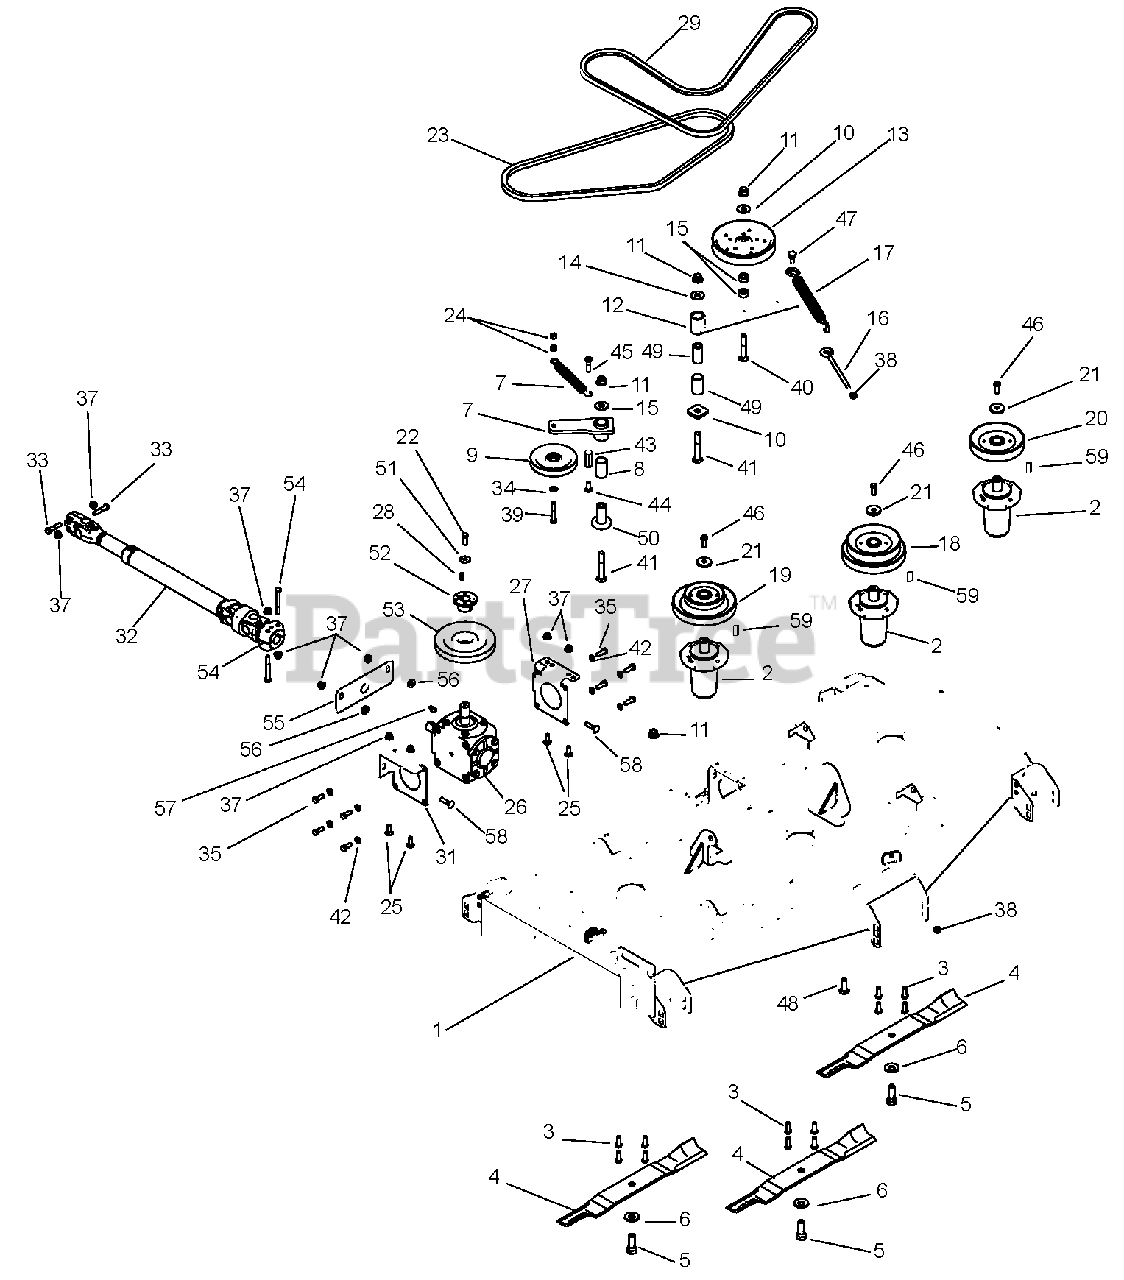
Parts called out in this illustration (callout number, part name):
1	Weldment, 60" Side Discharge Deck (OFM)
2	Assembly, Spindle
3	Bolt, Hex .38-16 x 1.00 EP30
4	Blade, Mower (20.50")
5	Bolt, Hex .62-18 x 1.75 Grade 8
6	Washer, Bellville .63 x 1.625 x .14
7	Weldment, Idler Pivot Arm
8	Bushing, 1.00 x 1.125 x 1.937
9	Sheave, .38" ID x 5.00" OD V-Idler
10	Washer, Flat .640 x 1.75 x .250
11	Nut, Nyloc Flange .50-13
12	Idler Pivot Arm Weldment- Black
13	Idler, Flat-Pulley 6.75 x .510
14	Washer, Flat-Steel .563 x 1.38 x .109
15	Bushing, Spacer .502 x .997 x .50
16	Bolt, .38-16 x 5.50 .62 Diameter Eye
17	Spring, Extension
18	Pulley, Double 1" ID x 6.75" OD
19	Pulley, Double 1.0" ID x 6.75" x 4.25" OD
20	Pulley, V-1" ID x 6.75" OD
21	Washer, Flat Steel .406 x 1.50 x .245
22	Bolt, Hex .38-16 x 1.00 EP30
23	Belt, B 63.00 Raw Cogged
24	Nut, Locking-Center .38-16
25	Bolt, Round Head Square Neck .38-16 x 1.25
26	Gear Box,Right Angle 1.05 x 1.0
27	Bracket, Gear Box Mounting Left Hand
28	Key, Straight .25 x .75 x .25
29	Belt, B 86.00 Wrapped
30	Washer, Flat Steel 1.00 x 1.505 x .062
31	Bracket, Gear Box Mounting Right Hand
32	Shaft, PTO Drive Assembly
33	Bolt, Hex .38-16 x 1.175
34	Washer, Flat Steel .406 x .812 x .065
35	Bolt, Hex .38-16 x 1.00 Grade 8 EP30
36	Spring, Extension
37	Nut, Nylon Locking Flange .38-16
38	Nut, Hex .38-16
39	Bolt, Hex .38-16 x 2.25
40	Bolt, Roundhead Squareneck .50-13 x 3.00
41	Bolt, Roundhead Squareneck .50-13 x 3.50
42	Washer, Lock .375 x .115
43	Nut, Coupling .375-16 x 1.75
44	Bolt, Roundhead Squareneck .38-16 x 1.00
45	Bolt, Hex .38-16 x 1.50
46	Bolt, Hex 3/8-16 x 2.75 Grade 5
47	Bolt, Shoulder Hex .38-16 x .30
48	Bolt, Roundhead Squareneck .50-13 x 1.50
49	Bushing, Spacer, .505/.500 x .999/.996 x 2.05/2.03
50	Pedestal, Bearing
51	Washer, Flat Steel .375 x 1.125 x .065 YWZC
52	Bushing, Taper 1" Shaft
53	Sheave, Taper Bushing 6.45" O.D.
54	Bolt, Hex .38-16 x 3.00 YWZC
55	Cover, Gearbox Bearing
56	Washer, Flat Steel .390 x .88 x 18 YWZX
58	Bolt, Roundhead Squareneck .38-16 x 1.50 YZ
59	Key, Square .25 X .25 X 1.00
